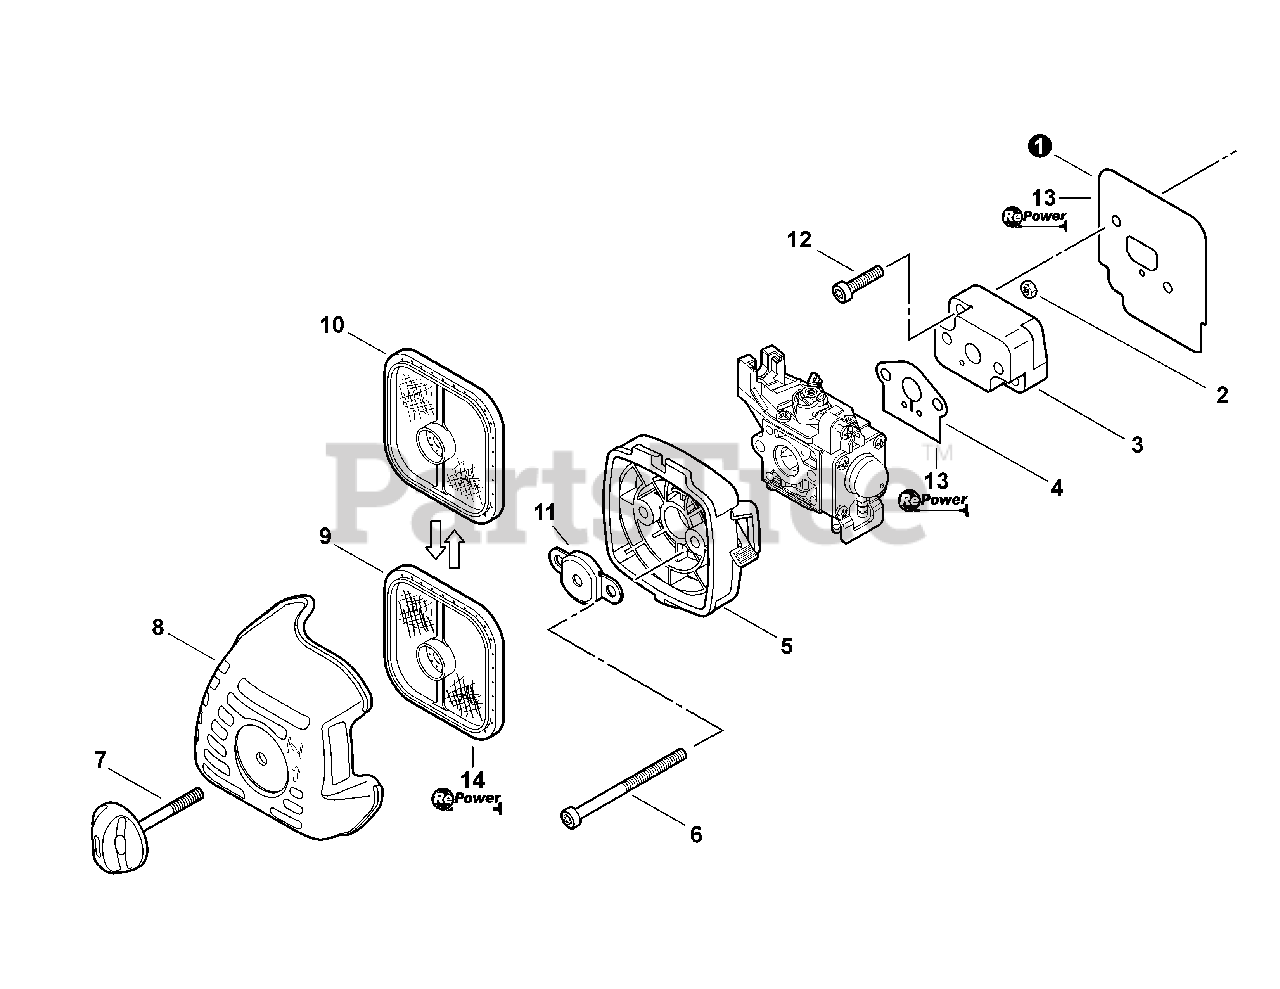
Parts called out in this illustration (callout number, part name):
1	HEAT SHIELD, INTAKE
2	NUT M5
3	INSULATOR, INTAKE
4	GASKET, INTAKE
5	CASE ASSY, AIR FILTER
6	BOLT, TORX 5×65
7	THUMBSCREW
8	COVER, AIR FILTER
9	FILTER, AIR - DOUBLE LAYER
10	FILTER, AIR - SINGLE LAYER
11	PLATE, PREVENT
12	BOLT, TORX 5×20
13	GASKET KIT
14	TUNE-UP KIT - REPOWER
